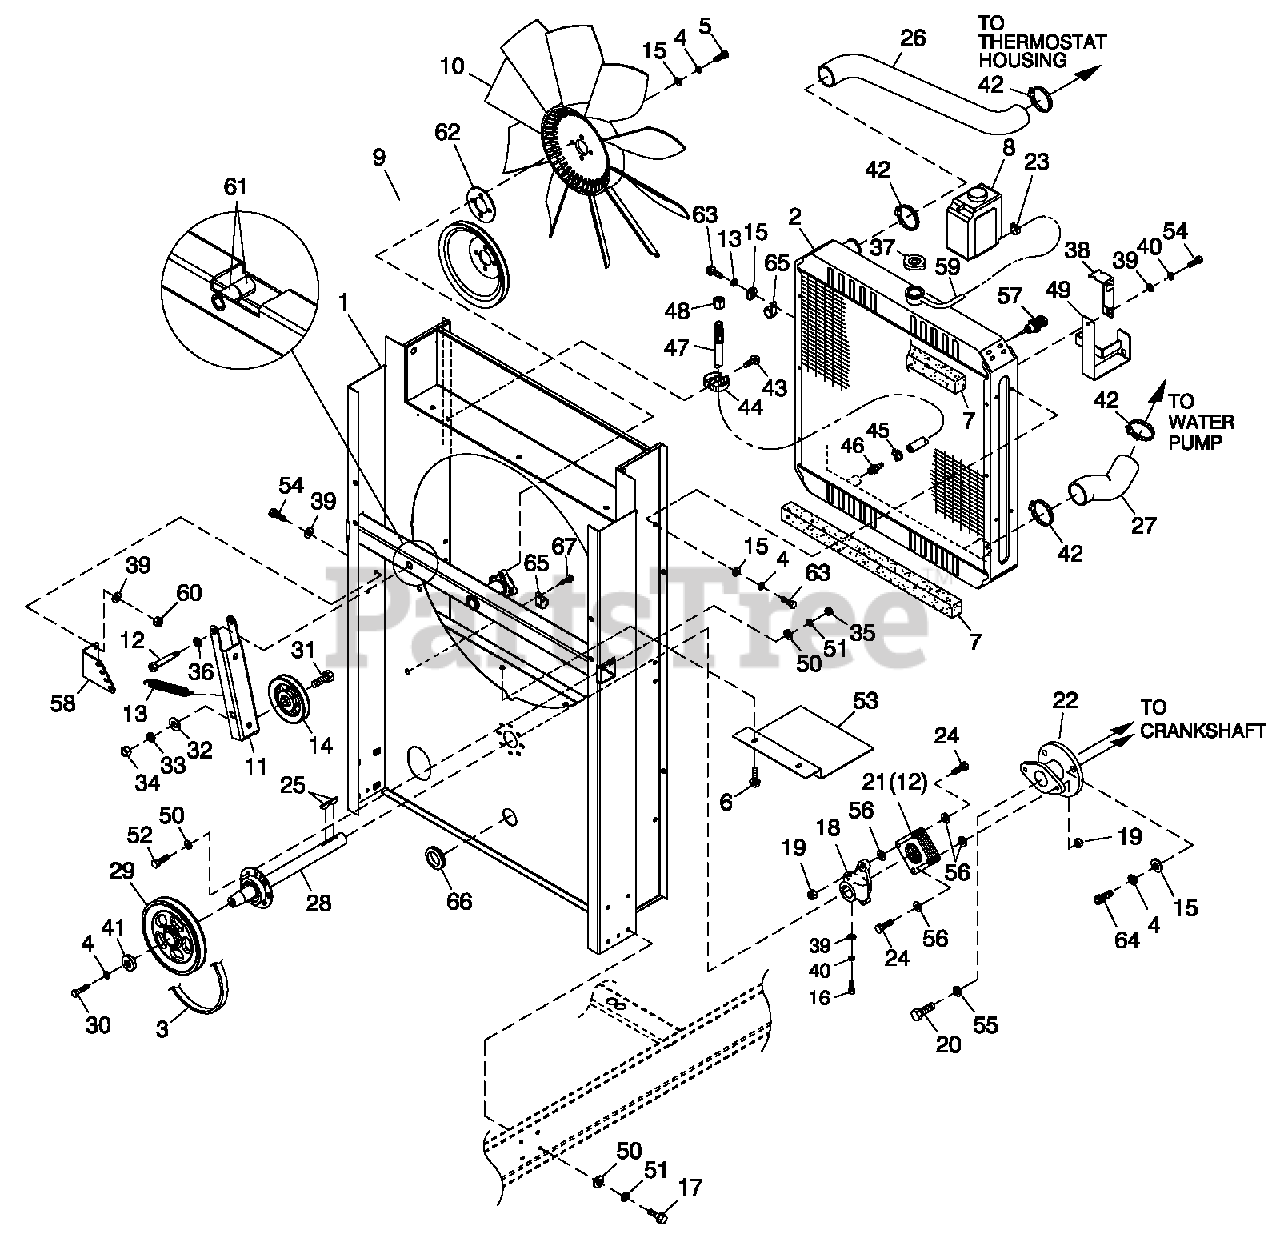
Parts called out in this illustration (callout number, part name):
1	WELDMENT RADIATOR SUPPORT C5
2	RADIATOR 680 X 680 X 70 CPL
3	V-BELT 31/64" X 62-3/8"
4	WASHER LOCK M10
5	SCREW HHC M10-1.5 X 30 C10.9
6	SCREW THF M6-1 X 16 N W A Z/JS
7	TAPE FOAM 1 X 1 (26.75" LG)
8	TANK COOLANT RECOVERY
9	PULLEY FAN V-GROOVE 9"
10	FAN 26" LH ROTATION
11	ARM BELTTENSIONER
12	SHOULDER BOLT 1/2 X 2-1/4"
13	SPRING TENSION CPL
14	PULLEY V-BELT 4" FLANGED
15	W ASHER FLAT 3/8-M10 ZINC
16	SCREW HHC M 8-1.25X 45C 8.8
17	SCREW HHFC M 6-1.0X 20 G8.8
18	HUB FLEX PLATE
19	NUT HEX LOCK 5/16-24 NY INS
20	SCREW HHC M 12-1.5X 60G 8.8
21	DISK FLEX
22	COUPLING HUB FLEX (MACH)
23	CLAMP HOSE BAND 1/4
24	SCREW HHC 5/16-24X1.124
25	KEY WOODRUFF 4 X 1 9 D
26	HOSE RADIATOR UPPER CPL
27	HOSE LOWER RAD CPL C5 6.8L
28	ASSY BRG/SHAFT CPL FANDRIVE
29	PULLEY 6.5" DIA MACHINED (6.8L 100KW)
30	SCREW HHC M 10-1.5X 30G 8.8
31	SCREW HHC 1/2-13X 2" G8
32	W ASHER FLAT 1/2 ZINC
33	W ASHER LOCK 1/2
34	NUT HEX 1/2-13 STEEL
35	NUT HEX M 6X 1.0 G8 YEL CHR
36	W ASHER NYLON .50 X .87 X .06
37	CAP RADIATOR 13 PSI
38	BRACKET, SIGNAL CONDITIONER
39	W ASHER FLAT 5/16-M8 ZINC
40	W ASHER LOCK M8-5/16
41	SPACER .5 X 1.5 X .25 STL/ZINC
42	CLAMP HOSE #28 1.32-2.25
43	SCREW HHTT M4-0.7 X 8 BP
44	SPRING CLIP HOLDER .37-.62
45	CLAMP HOSE .38-.87
46	BARBED STR 3/8 NPT X 3/8
47	HOSE DRAIN ASSY 28"
48	CAP HEX 1/4 NPT BRASS
49	BRACKET COOLANT TANK
50	W ASHER FLAT 1/4-M6 ZINC
51	W ASHER LOCK M6-1/4
52	SCREW HHC M 6-1.0X 20G 8.8
53	SHIELD RADIATOR
54	SCREW HHC M 8-1.25X 20G 8.8
55	W ASHER LOCK M12
56	W ASHER FLEX (THIN)
57	PROBE COOLANT LEVEL 3/8-18NPTF
58	BRACKET TENSIONER SPRING
59	HOSE 9/32 ID (43"LG)
60	NUT HEX LOCK M8-1.25 NY INS
61	BEARING SLEEVE 1/2/ X 3/4 X 1
62	SPACER CPL COOLING FAN 1/8"
63	SCREW HHC M 10-1.5X 20C 8.8
64	SCREW SHC M10-1.5X 35 G12.9
65	CLAMP S T U V N L .62 X . 406 Z
66	GROMMET 1.37 X .06 X 1.00
67	SCREW HHTT M 6-1.0X 16ZYC
